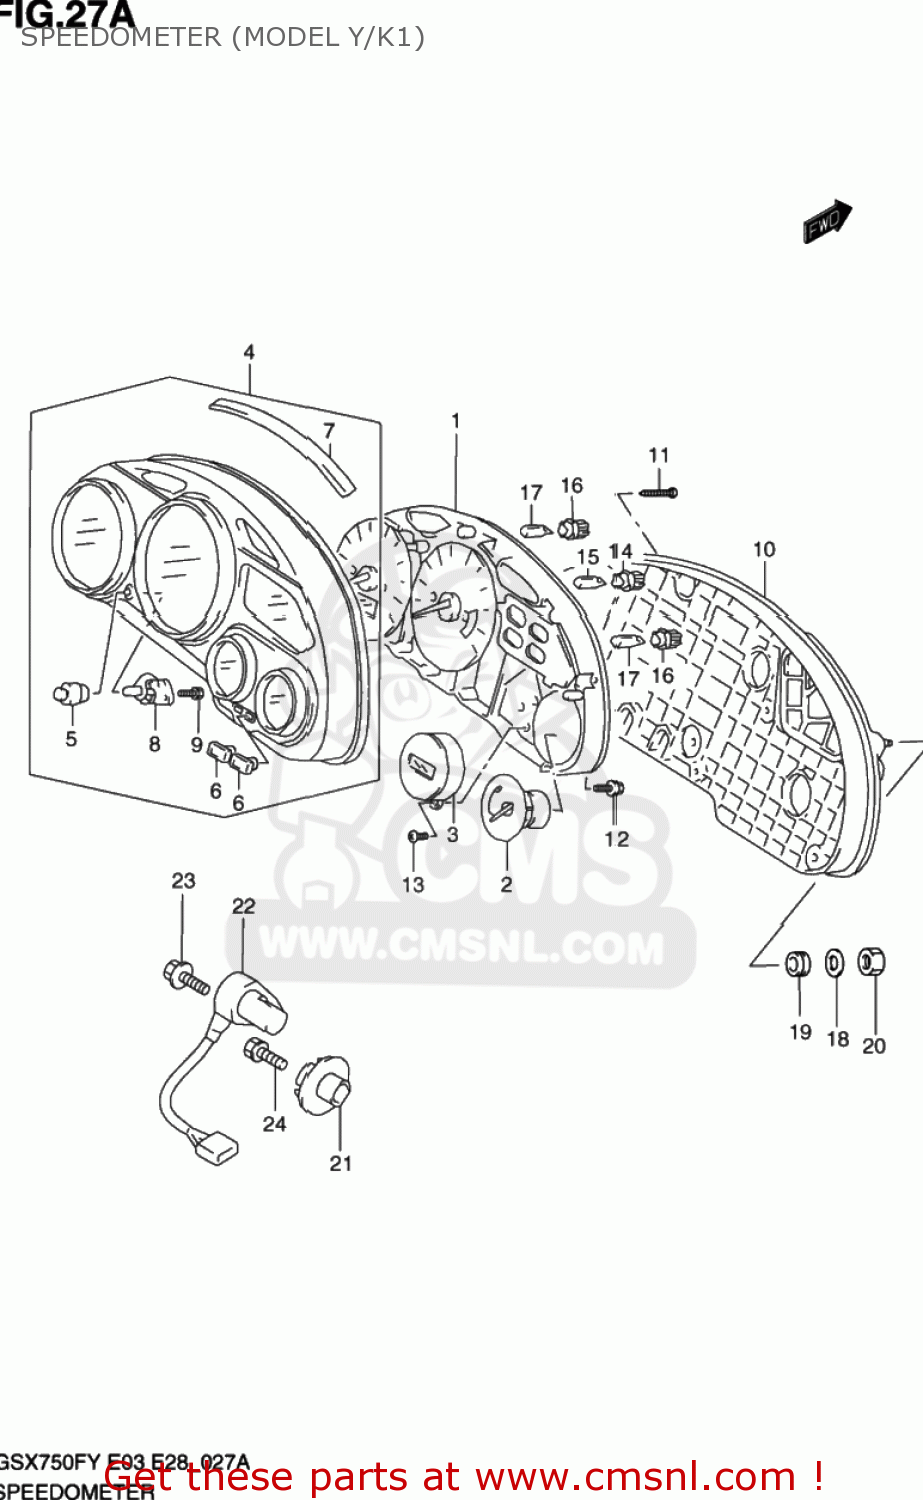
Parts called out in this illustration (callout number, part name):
1	SPEEDOMETER
2	FUEL,METER
3	CLOCK ASSY
4	VISOR ASSY
5	SWITCH,GUM
6	SWITCH,GUM
7	PACKING (NAS)
8	ATTACHMENT,SWITCH
9	SCREW(3X10)
10	CASE ASSY
11	SCREW
12	SCREW
13	SCREW
14	SOCKET(T:6.5)
15	BULB(12V1.7W,T6.5)
16	SOCKET
17	BULB(14V1.4W,T5)
18	WASHER(6.5X22X1.6)
19	CUSHION
20	NUT 6MM
21	ROTOR,SPEED
22	SENSOR,SPEED
23	BOLT
24	BOLT
